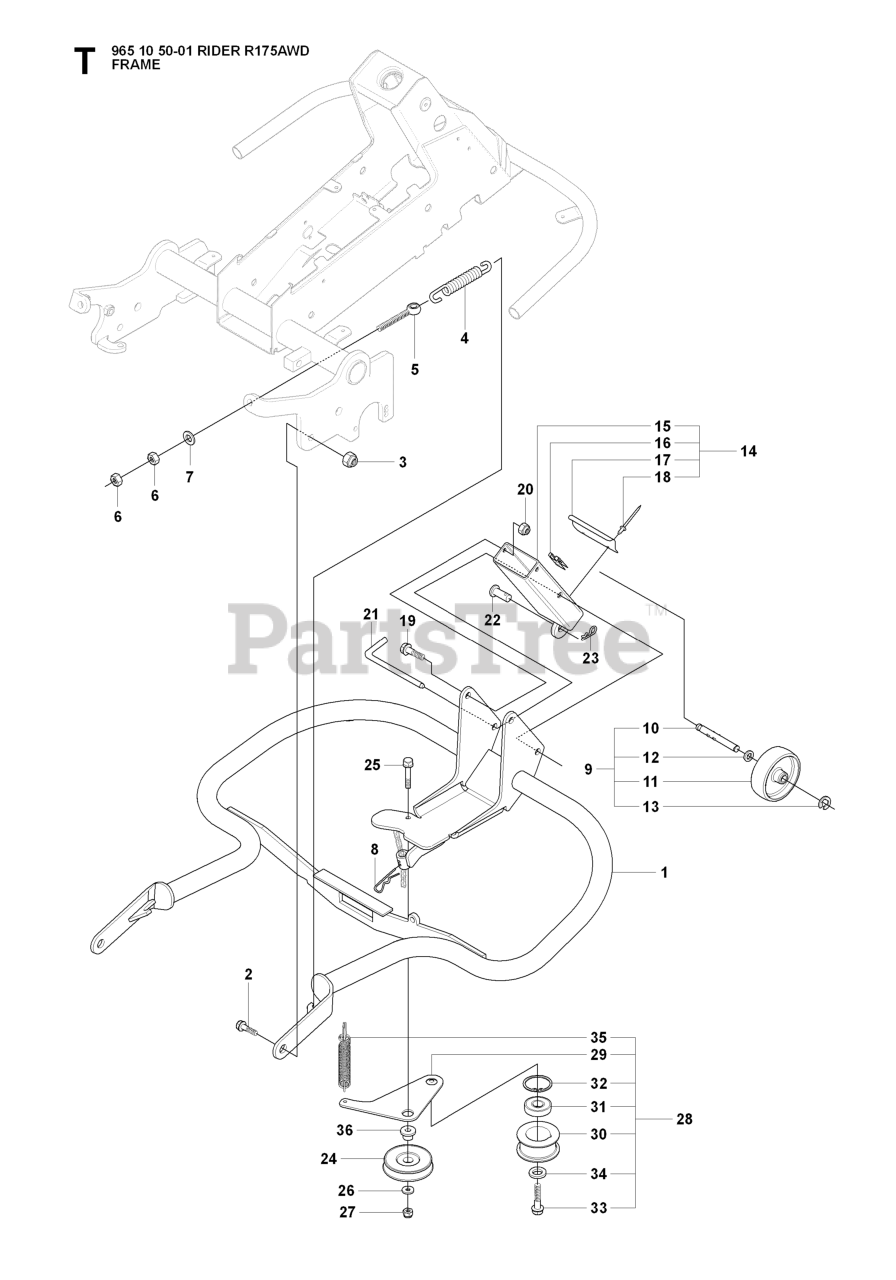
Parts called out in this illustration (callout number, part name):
1	DECK FRAME
6	NUT
7	WASHER
9	WHEEL ASSY
13	RETAINING RING
20	LOCKNUT M8
27	LOCKNUT M8
28	BELT TENSIONER ASSY
30	%PULLEY
31	BALL BEARING 6004-2RS1
32	RETAINING RING
